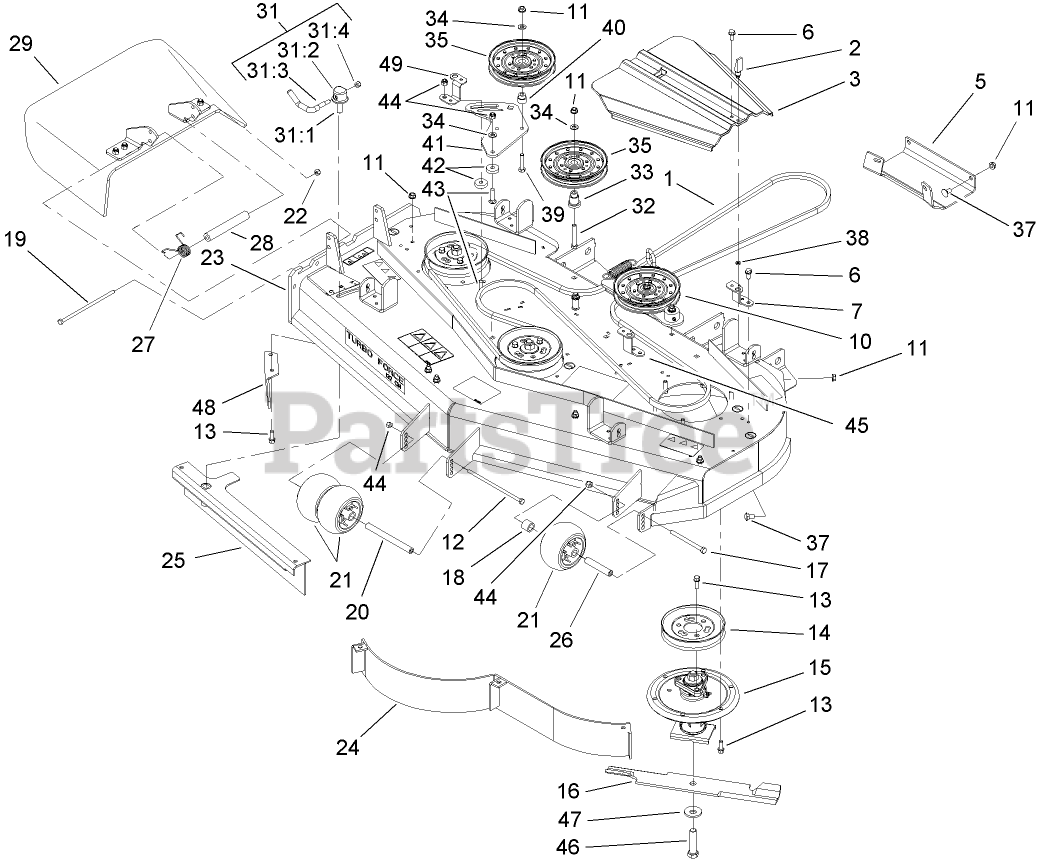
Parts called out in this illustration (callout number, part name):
1	BELT-V
2	LATCH-SWELL
3	COVER-BELT
5	Plate-Skid
6	SCREW-HWHTF
7	BRACKET-COVER, TALL
10	IDLER ASM
11	NUT-HHF, WHIZ
12	SCREW-HH
13	SCREW-HWH
14	PULLEY
15	SPINDLE ASM
16	BLADE-18IN, HI FLOW
17	SCREW-HH
18	TUBE-SPACER
19	SCREW-HH
20	SPACER-WHEEL
21	ROLLER-SCALP, ANTI
22	NUT-LOCK, NI
23	DECK DECAL ASM
26	TUBE-SPANNER
27	SPRING-TORSION
28	SPACER
29	RUBBER DEFLECTOR ASM
31	LEVER ASM
31:1	Screw-Lock
31:2	CAP-LOCK
31:3	Lever-Lock
31:4	NUT-LOCK, NI
32	SCREW-HH
33	MOUNT-PULLEY
34	WASHER-FLAT
35	Idler-Flat
37	SCREW-CARR
38	WASHER
39	SCREW-HH
40	BUSHING-IDLER
41	PLATE-IDLER
42	Spacer
43	SCREW-CARR
44	NUT-LOCK, NI
45	Bracket-Cover, Belt
46	Screw-Cap
47	Washer-Blade Bolt, Heavy
48	BAFFLE-DISCHARGE
49	BRACKET-COVER, SHORT
